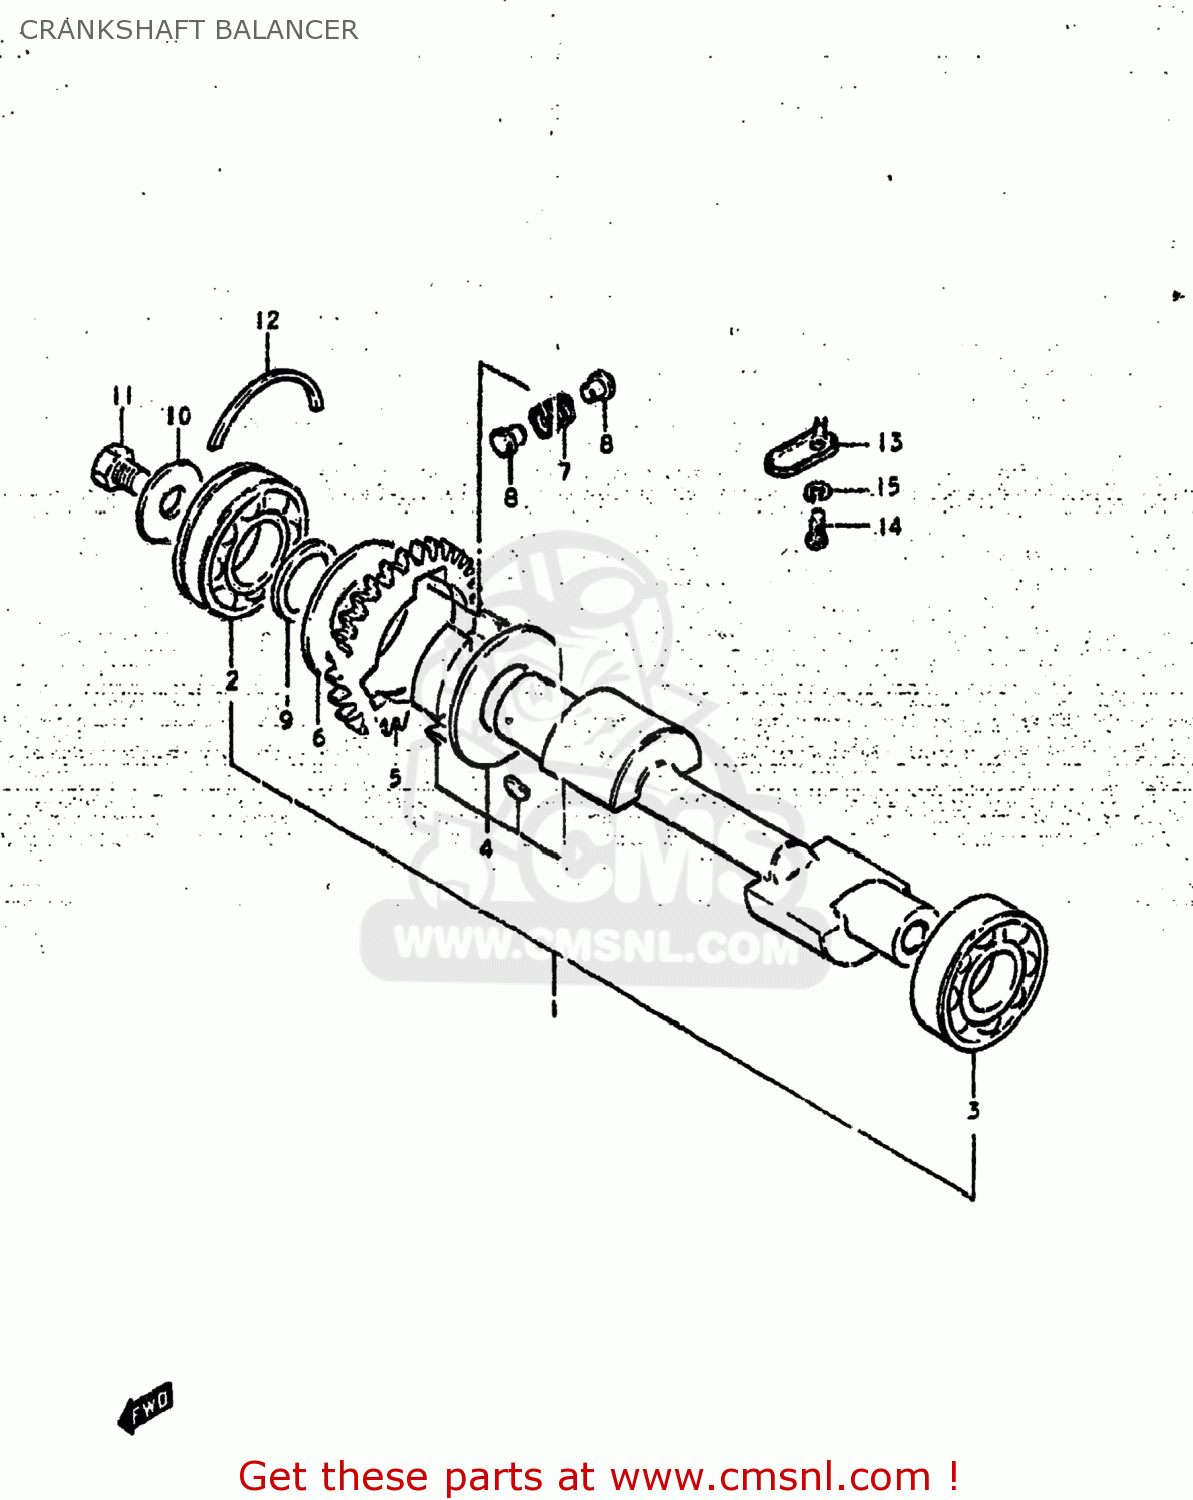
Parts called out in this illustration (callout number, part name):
1	BALANCER,CRANKSHAFT
2	BEARING
3	BEARING
4	CLUTCH SET,STARTER
5	GEAR,CRANK BALANCER DRIVE
6	WASHER (31X70X3)
7	SPRING
8	PIN
9	WASHER
10	WASHER
11	BOLT ,12X16
12	C RING
13	PLATE, OIL RESERVE
14	SCREW
15	LOCK WASHER
